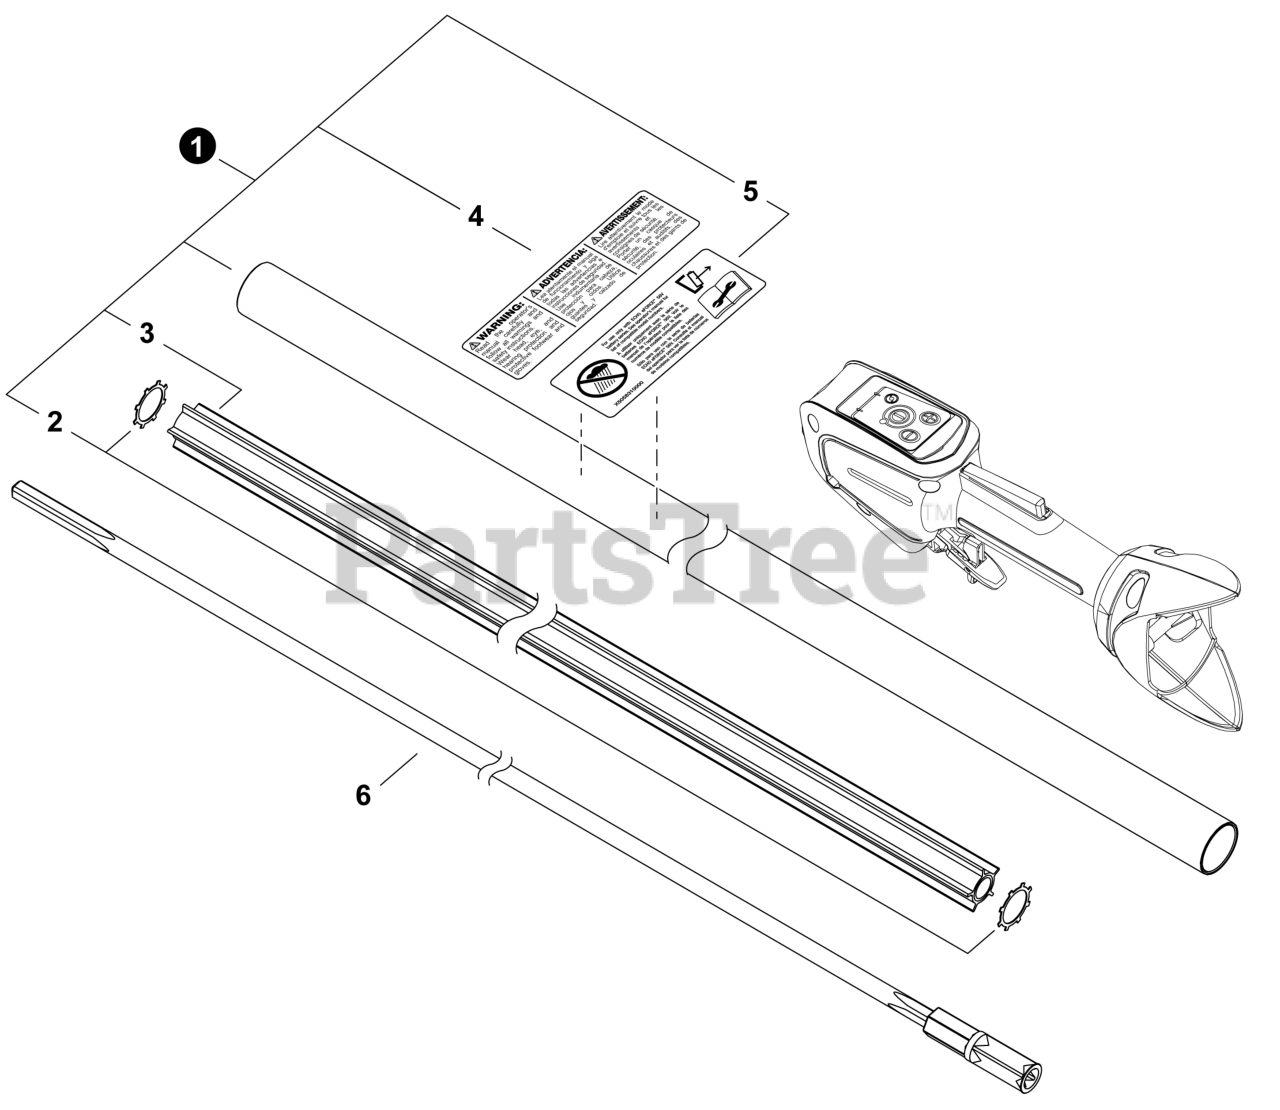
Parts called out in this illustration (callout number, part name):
1	MAIN PIPE ASSY
3	LINER - FLEXIBLE
4	LABEL - CAUTION - ISO
5	LABEL - CAUTION - UL
6	DRIVESHAFT - FLEXIBLE
